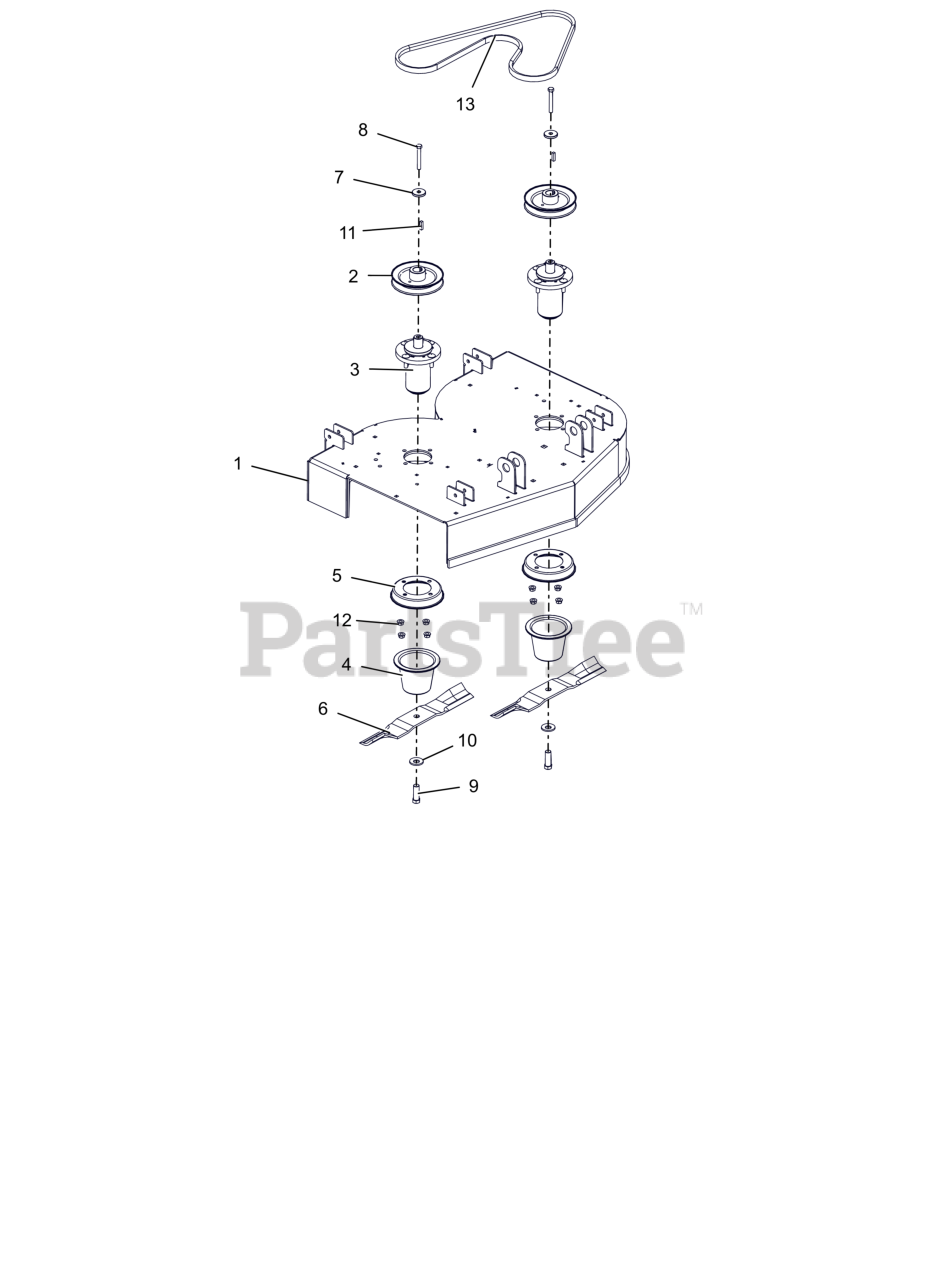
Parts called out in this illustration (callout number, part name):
1	KIT, SVC 32" DECK W DECALS
2	PULLEY, V-1.00 ID X 5.75 OD (BLACK)
3	ASM, MAINT FREE ALUM SPINDLE
4	GUARD, SPINDLE LOWER
5	GUARD, SPINDLE TOP
6	BLADE, 16.19" MOWER (HI-LIFT)
7	RETAINER, SHEAVE
8	BLT, HEX .38-16X2.75 G8 ZCC
9	BLT, HEX .62-18X1.75 G8 ZCC
10	WSHR-BLVL .669X1.535X.138
11	KEY, SQ .25X.25X1.00 RC 40-50
12	NUT-LK-CTR-FLG .375-16 GF ZCC
13	V-BELT, 5L RAW EDGE EPDM
